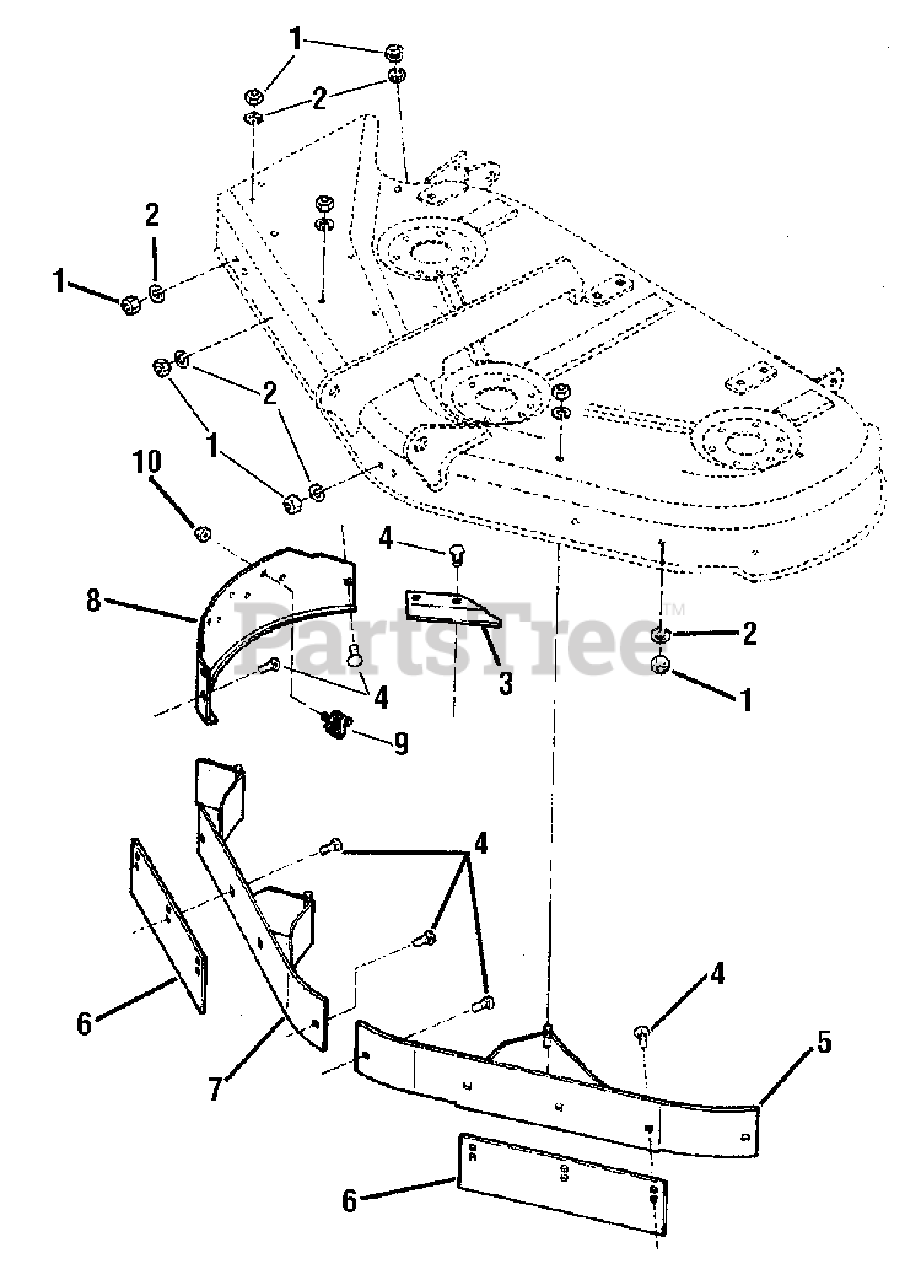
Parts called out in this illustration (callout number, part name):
1	NUT, Hex, 5/16-18
2	LOCKWASHER, 5/16
3	MOWER LIP, Rear
4	CARRIAGE BOLT, 5/16-18 x 3/4
5	BAFFLE & DEFLECTOR ASSEMBLY, L. H.
7	BAFFLE & DEFLECTOR ASSEMBLY, R. H.
8	PLATE, Mulcher
9	LEAF SHREDDER
10	NUT,Hex Nylock, 5/16-18
